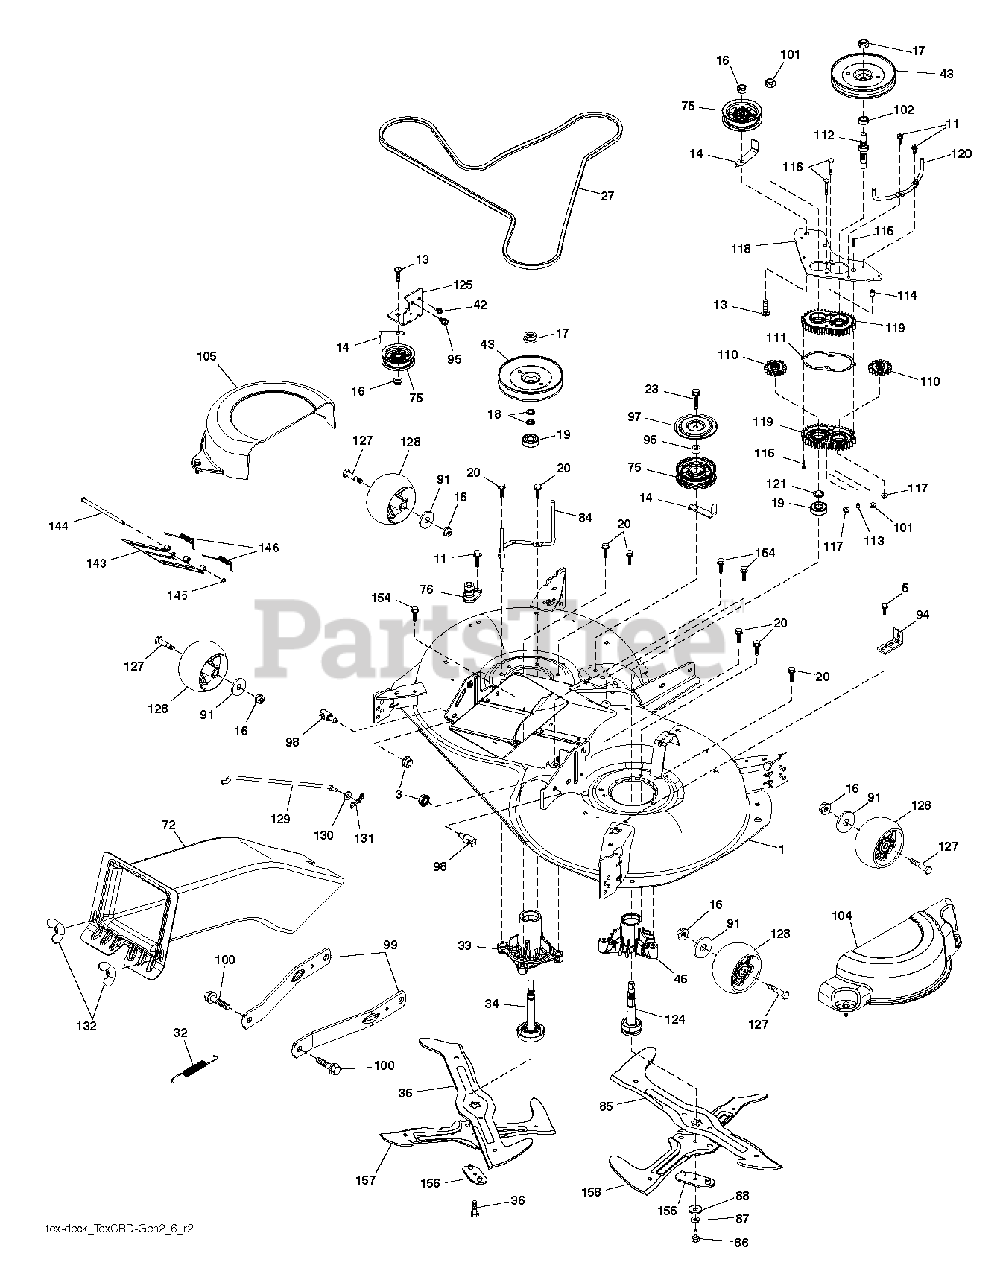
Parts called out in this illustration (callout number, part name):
3	NUT LOCK HEX FLANGE 5/16-18
5	BOLT.5/16HEX.WHS.HD
11	SCREW.1/4-20X5/8
13	BOLT.3/8-16X1.50
14	KEEPER, BELT IDLER
16	NUT LOCK FLG 3/8-16 UNC
17	NUT.FLANGE.LOCK.TOP
18	WASHER.SPACER.MANDREL
20	SCREW, WASHER HEAD
23	SCREW LT
27	BELT BELT. ELECTRIC M
32	SPRING 107CM 97CM ELE
33	HOUSING MANDREL
34	SHAFT.ASM.MDRL.N/GREASE.38
35	BLADE.3N1.LH.CRD
36	BOLT.WASHER.ASM.7/16-2
42	SCREW
43	PULLEY PULLEY MANDREL
45	HOUSING.MANDREL
72	97/107.TEX.CRD.UPPER CHUTE(22)
75	FLAT IDLER PULLEY
84	KEEPER KEEPER. LH MAN
85	BLADE.3N1.RH.CRD
86	BOLT.3/8-24X1.25GR8. LHTHRD
87	LOCKWASHER
94	BRKT.CLUTCH.CABLE
95	SCREW, 3/8-16X3/4
98	STUD.FASTNER.W/ANTI-ROTATE
99	ARM.SUSPENSION.MOWER.R
100	BOLT.SHOULDER
101	NUT.CROWNLOCK.9/16 -18.UNC
102	SPACER BEARING
110	RP.CRD.GEAR.OUTPUT
111	GASKET GASKET GEARCAS
113	PLUG PLUG OIL
114	VALVE VALVE RELIEF
115	Screw
116	BOLT.CARIGE.SS.1/4-20X1.75GR5
117	NUT T
118	ARM ARM. CLUTCHING 10
119	GEARCASE GEARCASE SUB
120	KEEPER KEEPER. RH MAN
121	Washer, .687ID X 1OD X 062 THK
124	Mandrel Shaft, Non/Greaseable
125	Bracket
127	BOLT.SHOULDER.3/8-16X3-5/8
128	WHEEL. GUAGE RALLY
129	ROD ROD. SWAY CRD GEN
130	WASHER
131	PIN.COTTER.5/16.BOW TI
132	KNOB.HANDLE.3/8.TRI-POINT.BLAC
143	COVER DOOR.107 CM CRD
144	Hinge Pin
146	SPRING SPRING EZ MULC
154	SCREW T30 1420 X
156	ADAPTER ADAPTER.CROSS
